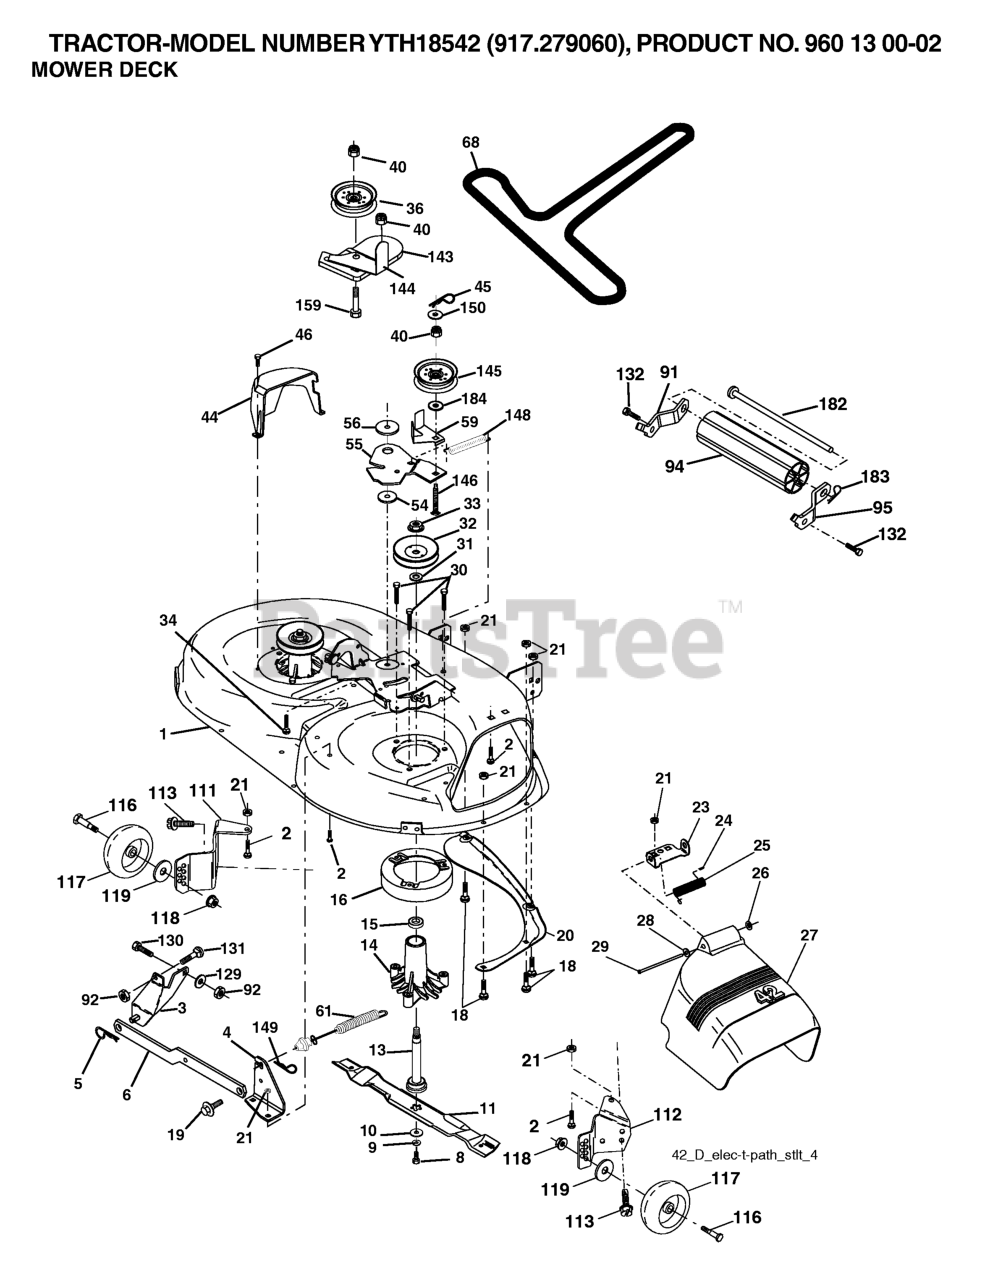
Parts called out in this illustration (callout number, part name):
1	DECK SVC 42"
2	RP BOLT 5/16-18 X3/4 ZN/YEL GR
3	BRKT ASM SWAY BAR
4	BRACKET SWAY BAR 42" DECK
5	RETAINER-SPRNG RB
6	BAR SWAY DECK
8	BLADE BOLT
9	LOCKWASHER
10	WASHER.BLADE
11	42" HI-LIFT BLADE
13	SHAFT ASM VENT
14	HOUSING.MANDREL.VENTED (MACHD)
16	STRIPPER.MANDREL.ROUND.BLACK
18	BOLT
19	BOLT SHD 5/16-18
20	BAFFLE.VORTEX
21	LOCKNUT
23	BRKT, DEFL. MOWER
24	CAP-SLEEVE LT
25	SPRING TORSION
26	NUT PUSH M
27	SHIELD DEFLECTOR
28	Washer 11/32 x 5/8 x 16 Ga SD
29	ROD.HINGE
30	SCREW, WASHER HEAD
31	WASHER.SPACER.MANDREL
32	PULLEY/MANDREL
33	NUT, FLG TOPLOCK 9/16"
34	BOLT.3/8-16X1.50
36	FLAT IDLER PULLEY
40	NUT LOCK FLG 3/8-16 UNC
44	GUARD MANDREL LH BLACK
45	RETAINER M
46	SCREW.1/4-20X5/8
55	ARM IDLER 42" MOWER LT/YT
56	SPACER.RETAINER.MOWER
59	GUARD, BELT
61	SPRING EXT ELEC CLUTCH
68	V-BELT PRIMARY 42"
91	BRACKET ASM NOSEROLLER LH
92	NUT
94	NOSE ROLLER
95	BRACKET ASM NOSEROLLER RH
111	BRACKET, WHEEL
112	BRACKET, WHEEL
113	BOLT.5/16HEX.WHS.HD
116	BOLT M
117	WHEEL.GAGE.HALF.SPOKED
118	LOCKNUT
119	WASHER.5/16.FLAT.STE.STD.
129	WASHER
131	BOLT D
132	SCREW, 3/8-16X3/4
143	BRACKET, ARM IDLER
144	DNO KEEPER.BELT.42".CLUTCH.CBL
145	PULLEY
146	BOLT, CARRIAGE IDLER BLACK
148	IDLER RETURN SPRING
149	SPRING.RETAINER.YELLOW.ZINC
182	ROD ROLLER NOSE STANDARD
183	SPRING RETAINER
184	WASHER
